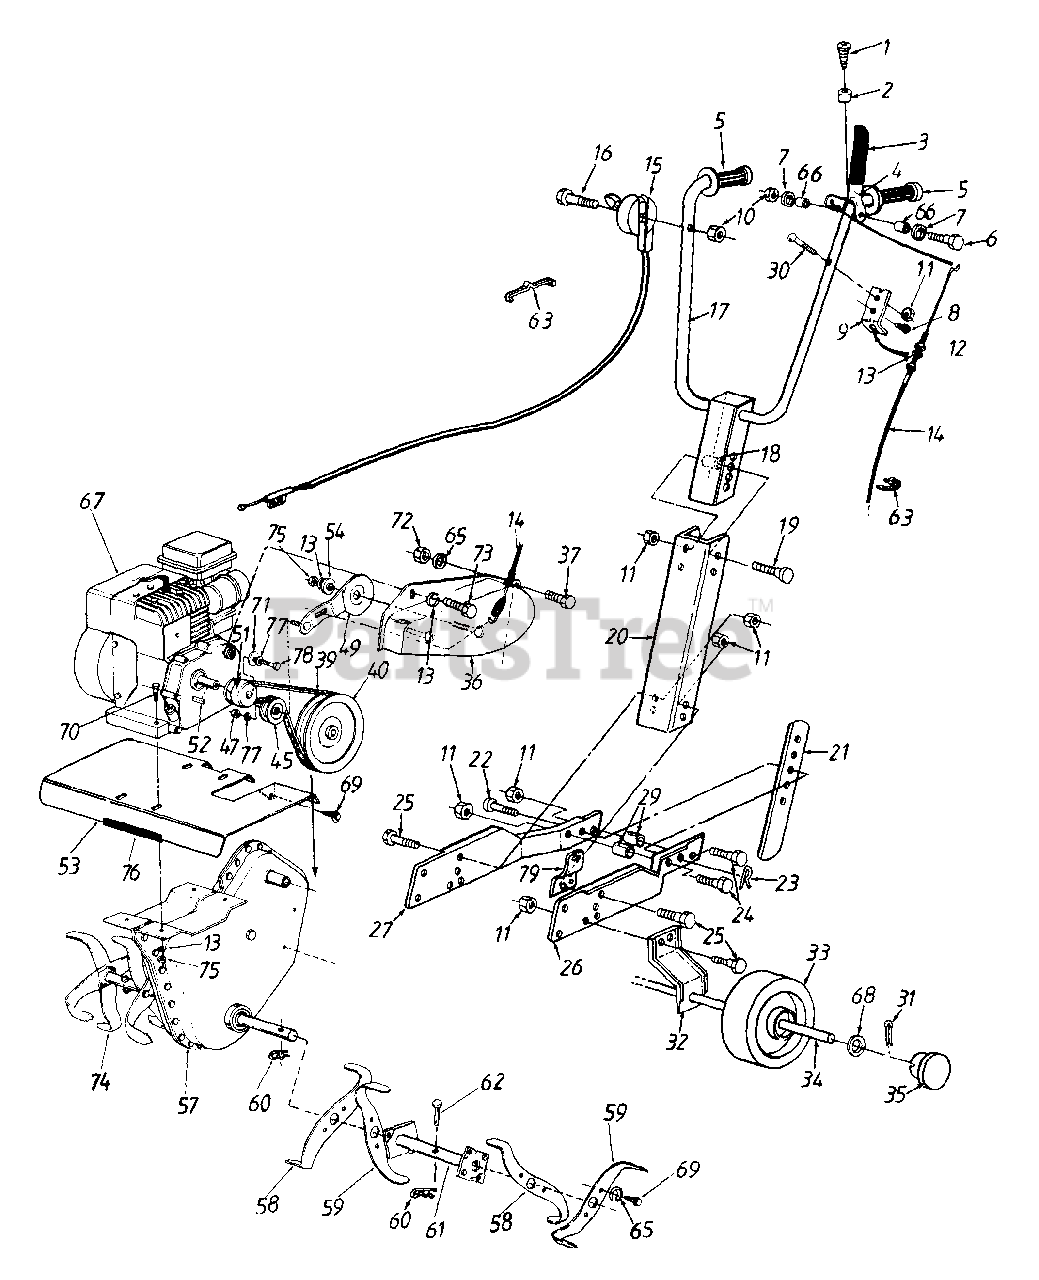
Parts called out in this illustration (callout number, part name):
1	Tap Scr. #10-16 x 1/2
2	Rubber Bumper
3	Vinyl Grip
5	Handle Grip
6	Hex Bolt 1/4-20 x 2"
7	Fl-Wash. 1/4" I.D.
8	Hex Tap Scr. 1/4-20 x 1/2
9	Cable Bracket
10	Lock Nut 1/4-20 Thd.
11	Lock Nut 5/16-18 Thd.
12	Hex Jam Nut 5/16-24 Thd.
13	L-Wash. 5/16" I.D.
14	Clutch Control Cable
15	Throttle Control
16	Hex Bolt 1/4-20 x 1-1/2"
19	Carr. Bolt 5/16-18 x 2-1/2"
23	Hairpin Cotter
24	Hex Bolt 5/16-18 x 1"
25	Hex Bolt 5/16-18 x 5/8"
29	Spacer
30	Hex Bolt 5/16-18 x 1-1/4"
31	Cotter Pin
34	Axle - Wheel
35	Hub Cap
39	V-Belt
40	Pulley - Chain Case
45	Flat Idler Pulley
47	Hex Jam Thd. L-Nut 3/8-24
49	Idler Arm Ass'y.
51	Engine Pulley
52	Square Key 3/16" x .75"
57	Chain Case Ass'y. Comp.
63	Cable Tie-Plastic
65	L-Wash. 1/4" I.D.
66	Spacer
67	Engine
68	Fl-Wash. 3/8" I.D.
69	Tap Scr. 1/4-20 x 1/2"
70	Hex Bolt 5/16-18 x 1-1/2"
71	Fl-Wash. 3/8" I.D. x 1" O.D.
72	Hex Nut 1/4-20 Thd.
73	Hex Bolt 5/16-24 x .5" Lg.
76	Trim Strip
77	L-Wash. 3/8" I.D.
78	Hex Bolt 3/8-24 x 1" Lg.
